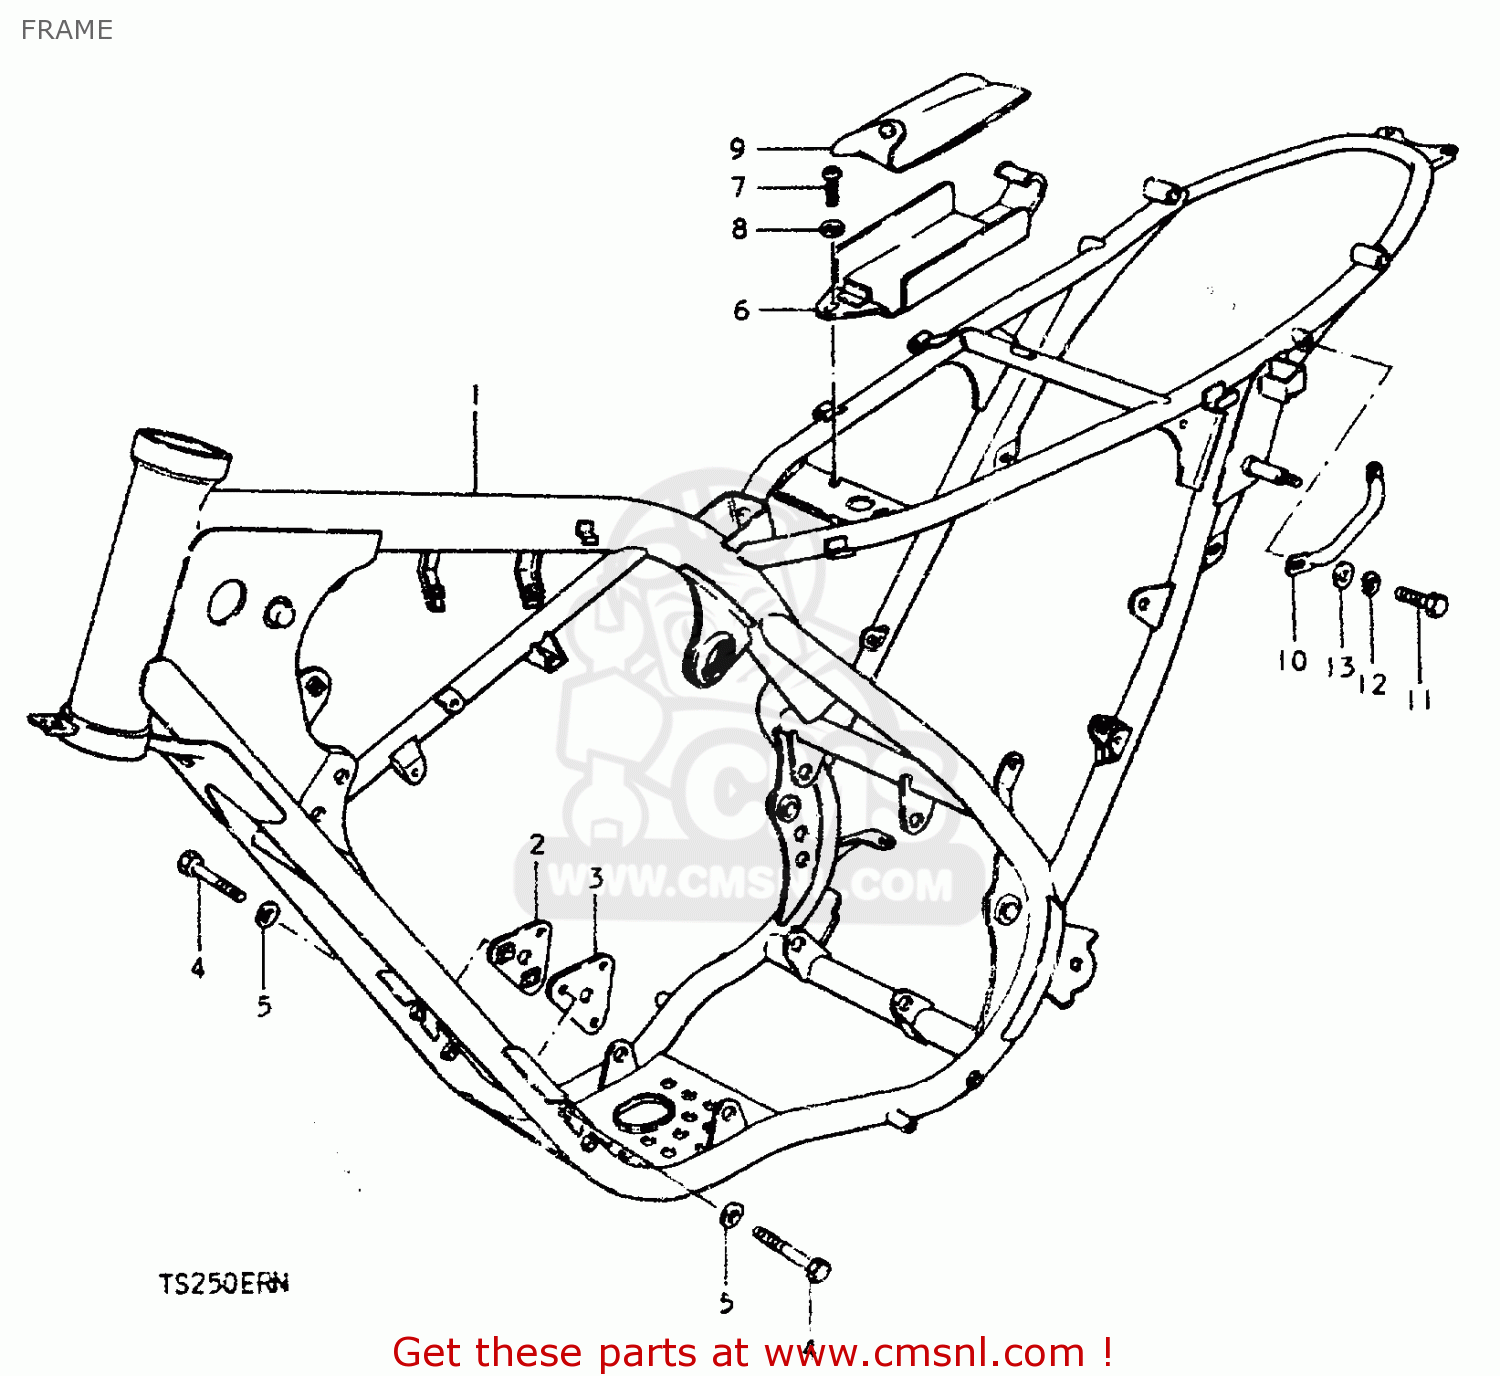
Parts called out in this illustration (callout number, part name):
1	FRAME
2	PLATE,ENGINE MOUNTING
3	PLATE,ENG MTG,L
4	BOLT 8X55
5	WASHER
6	HOLDER,TOOL
7	SCREW
8	WASHER
9	TOOL SET
10	GRIP,FRAME HANDLE
11	BOLT
12	LOCK WASHER
13	WASHER
